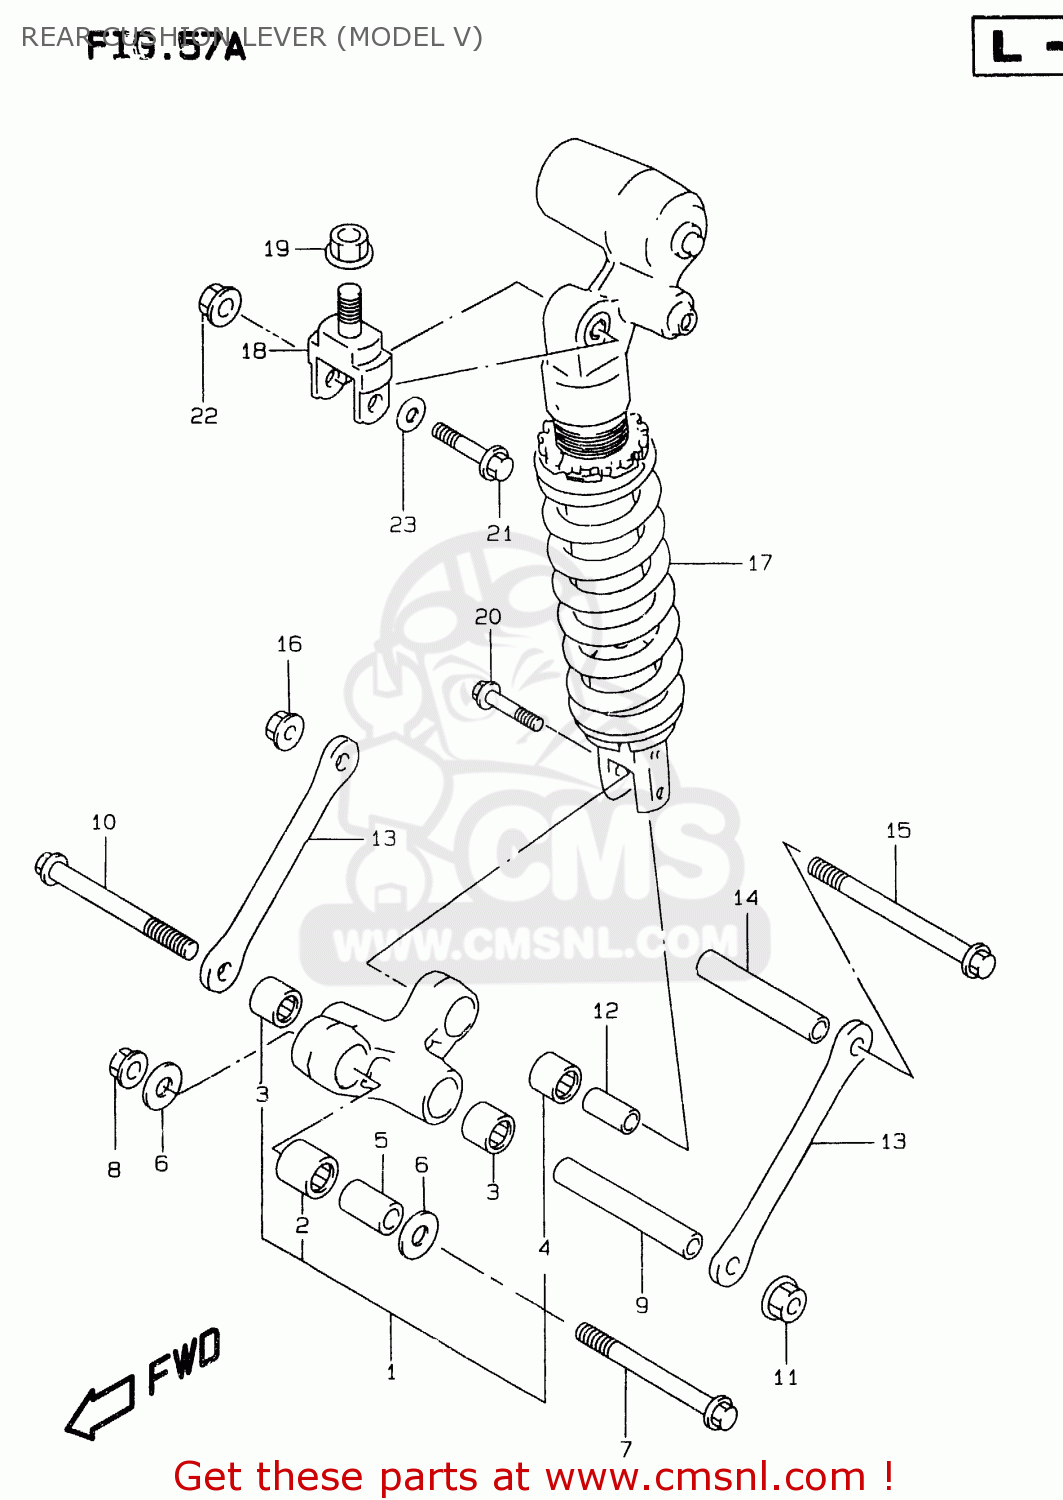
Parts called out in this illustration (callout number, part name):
1	LEVER SET,RR CUSHION
2	BEARING(20X27X30)
3	BEARING(17X24X20)
4	BEARING(17X24X26)
5	SPACER,RR CUSHION LEVER FR
6	WASHER
7	BOLT, FRONT
8	NUT 12MM
9	SPACER,RR CUSHION LEVER CTR
10	BOLT,RR CUSHION LEVER CTR
11	NUT 12MM
12	SPACER,RR CUSHION LEVER
13	ROD,RR CUSHION LEVER
14	SPACER,RR CUSHION LEVER CTR
15	BOLT,RR CUSHION LEVER CTR
16	NUT 12MM
17	ABSORBER ASSY,RR SHOCK
18	BRACKET,RR SHOCK ABSORBER UP
19	NUT
20	BOLT(10X44)
21	BOLT
22	NUT
23	WASHER (10X20X2.3)
